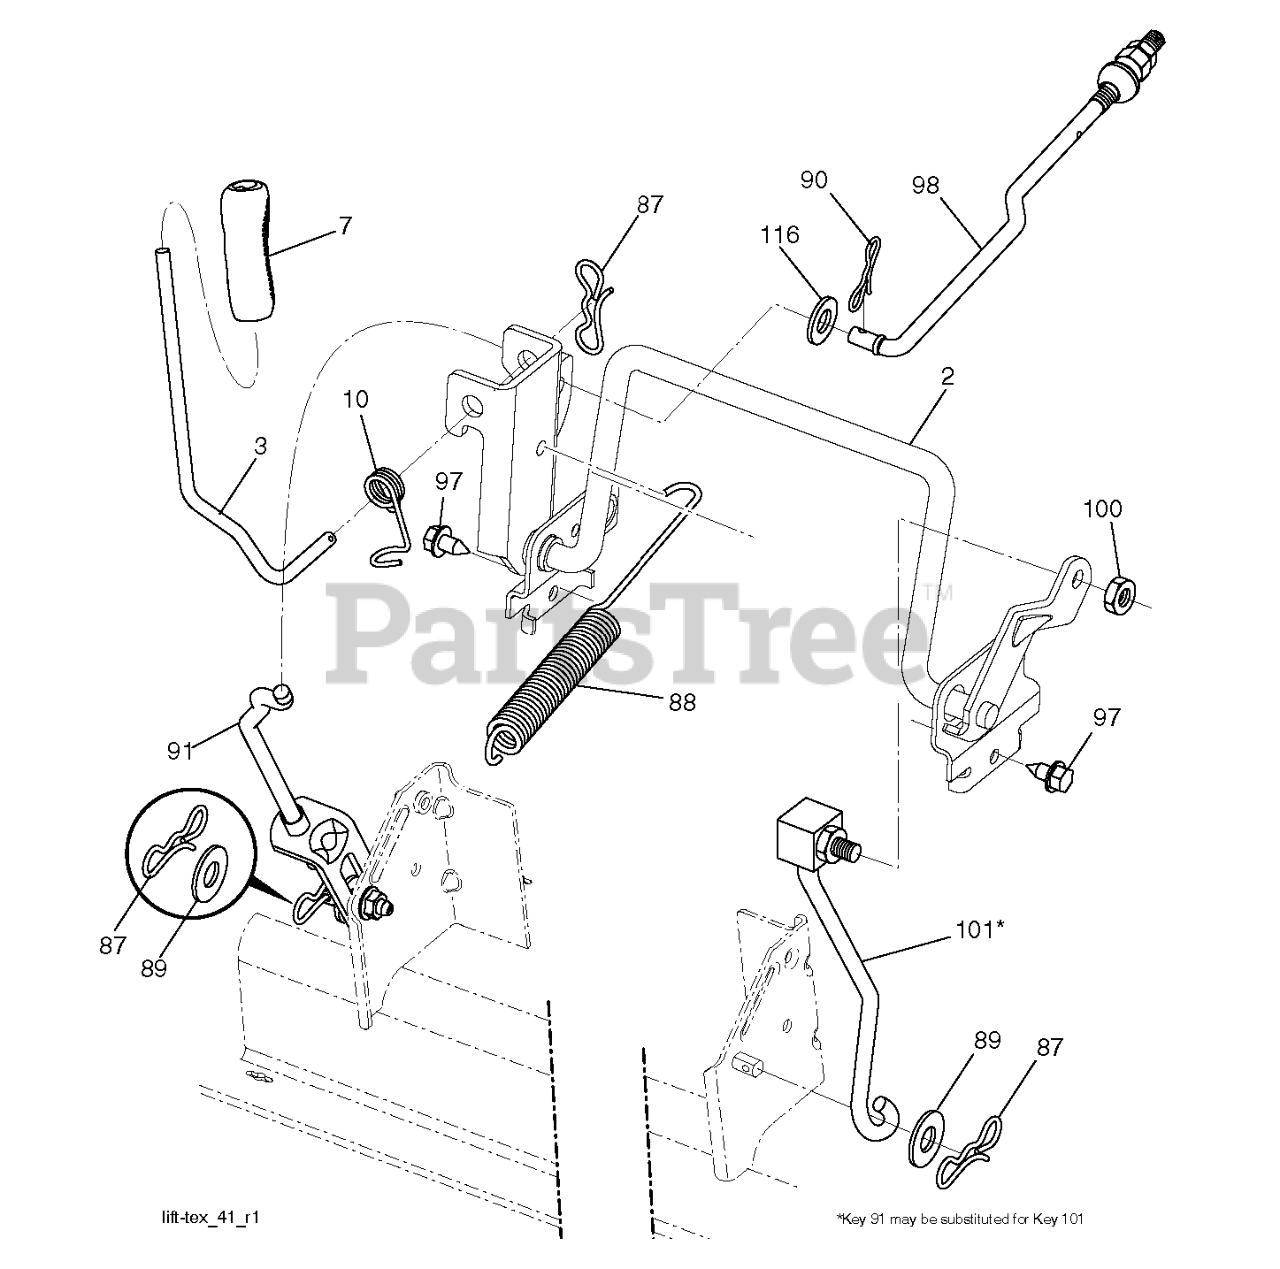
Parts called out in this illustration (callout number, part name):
2	SHAFT LIFT DECK WELD
3	LEVER.LIFT.HANDLE.LT
7	GRIP.HANDLE.LIFT.PVC.BLACK
10	SPRING.TORSION.LIFT.HANDLE
87	PIN.COTTER.7/16.BOW TI.
88	SPRING.DK.LIFT.97/107.TXCRDII
89	WASHER.CLEAR.ZINC
90	PIN.COTTER.5/16.BOW TI
91	LINK.ASM.LIFT.REAR
98	LINK.ASM.SUSP.FRONT.MW
100	LOCKNUT
101	LINK.ASM.LIFT.FIXE.38/42/46"
